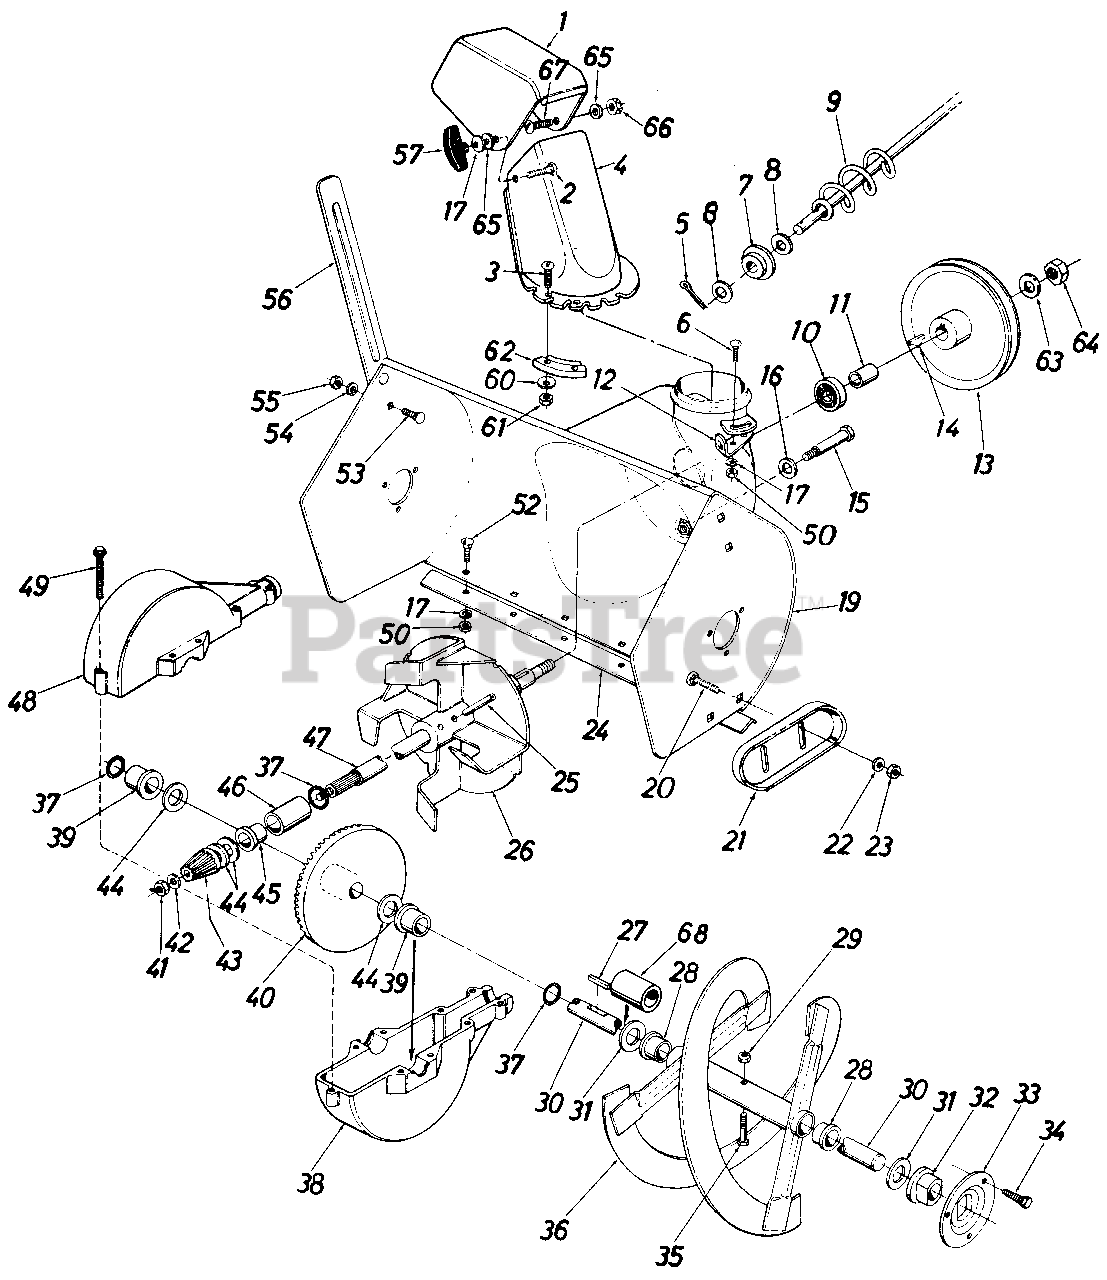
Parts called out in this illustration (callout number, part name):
1	Upper Chute
2	Carriage Bolt 5/16-18 x 1.0"*
3	Truss Mach. Scr. 1/4-20 x .75"*
4	Lower Chute
5	Cotter Pin
6	Carriage Bolt 5/16-18 x .75"*
7	Bushing
8	Fl-Wash. .385 I.D. x .62" O.D.
9	Chute Crank Ass'y.
10	Ball Brg. .62" I.D. x 1.38" OD.
11	Spacer .63" I.D. x .88" O.D. x.900" Lg.
12	Chute Crank Brkt.
13	1/2" "V"-Pulley .625" I.D. x 7.50" O.D.
13	5/8" "V"-Pulley .625" I.D. x 7.50" O.D.
14	#61 Hi-Pro Key 3/16" x 5/8" Dia.
15	Shld. Bolt .50" Dia. x 2.11"
16	Bell-Wash. .40" I.D. x .88" O.D. x .06
17	Bell-Wash. .34" I.D. x .88" O.D.
20	Carriage Bolt 3/8-16 x .62"*
21	Slide Shoe
22	Bell-Wash. 3/8" I.D.
23	Hex Jam Nut 3/8-16 Thd.
24	20" Shave Plate
24	24" Shave Flate
25	Spring Pin Spiral 1/4" Dia. x 1.50" Lg.
26	11" Dia. Blower Fan Ass'y.
27	Sq. Key 3/16" x 1.5" Lg.
28	Flange Brg. .75" I.D. x .88" O.D.
29	Hex Ins. L-Nut 5/16-18
30	Spiral Axle
30	Spiral Axle 1550 & 552)
31	Fl-Wash. .75" I.D. x 1.50" O.D. x .06
32	Flange Brg. w/Flats .755" I.D.
33	Bearing Housing
34	Hex Wash. Hd. Self-Tap Scr.- 0 5/16-24 x .62" Lg.
35	Hex Bolt 5/16-18 x 1.50" Lg.
36	20" Spiral Ass'v.-L.H.
36	20" Spiral Ass'y.-R.H.
36	24" & 26" Spiral Ass'y.-L.H.
36	24" & 26" Spiral Ass'y.-R.H.
37	O-Ring-3/4" I.D.
38	Bevel Gear Housing-Lower Half
39	Plastic Flange Brg. .755" I.D.
40	Bevel Gear
41	Hex Cent. L-Nut 5/16-24 Thd.
42	Fl-Wash. .34" I.D. x .62" O.D. x .06
43	Pinion Gear
44	Fl-Wash. .75" I.D. x 1.25" O.D. x .06
45	Flange Brg. .755" I.D.
46	Sleeve Brg. .755" I.D.
47	Blower Axle
48	Bevel Gear Housing-Upper Half
49	Hex Wash. Hd. Self-Tap Scr. 1/4-20 x 1.00" Lg.
50	Hex Nut 5/16-18 Thd.*
52	Carriage Bolt 5/16-18 x .62"-Lg.*
53	Camage Bolt 5/16-18 x .62" Lg. *
54	L-Wash. 5116" I.D.*
55	Hex Nut 5/16-18 Thd.*
56	Drift Cutter Bart
60	Fl-Wash. 1/4" I.D.
61	Hex L-Nut 1/4-20 Thd.*
62	Chute Flange Keeper
63	Fl-Wash. .64" I.D. x .94" O.D. x .06
64	Hex Jam Nut 5/8-18 Thd.
65	Fl-Wash. .344 I.D. x 1.125 O.D.
66	Hex L-Nut 5/16-18 Thd.
67	Truss Mach. Scr. 5/16-18 x-.75" Lg.*
68	Spacer
